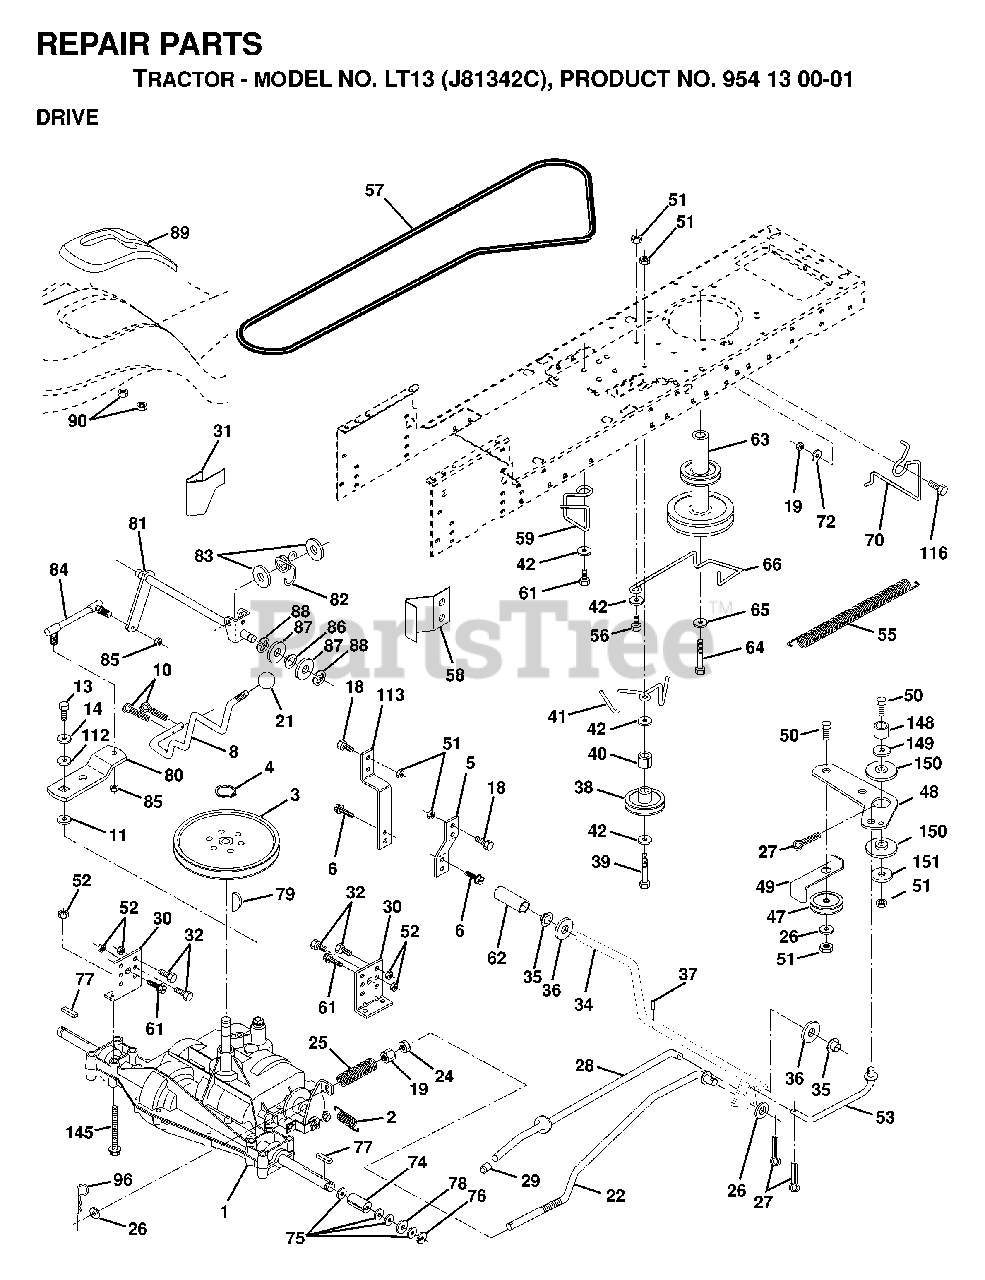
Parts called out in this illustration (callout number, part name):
2	SPRING,BRAKE RETURN
3	PULLEY TRANS
4	RETAINING RING LT
5	STRAP TORQUE
6	SCREW
8	ROD SHIFT FENDER
10	PIN COTTER
11	BLADE 42"
13	BOLT 1/4-28X3/4
14	LOCKWASHER
15	BOLT HEX 5/16-18 GR 5
19	NUT
21	KNOB.DELUXE.(PISTOL.GRIP).BLAC
22	ROD BRAKE
24	NUT
25	SPRING ROD LT
27	COTTER PIN
28	ROD BRAKE PARK LT
29	PLUNGER CAP
30	BRACKET TRANSAXLE
31	KEEPER BELT LH
32	BOLT
34	SHAFT, FOOT PEDAL
35	BEARING.NYLON
36	WASHER LT
37	DRIVE PIN
38	PULLEY.IDLER.FLAT
41	KEEPER, BELT IDLER
42	WASHER
47	IDLER PULLEY
48	BELLCRANK, CLUTCH
49	RETAIN BELT
50	BOLT
51	LOCKNUT
52	LOCKNUT
53	LINK, CLUTCH LT
55	SPRING, RETURN LT
59	KEEPER CENTER SPAN
61	SCREW
62	PEDAL COVER T
63	PULLEY ENGINE
64	BOLT
65	LOCKWASHER
66	KEEPER BELT ENGINE
70	KEEPER BELT ENG
74	SPACER AXLE
76	E-RING LT
77	SQUARE KEY
80	ARM SHIFT
82	SPRING,TORSION
83	WASHER
84	ROD,TIE
85	NUT LOCK CENTER 1/4 -28 FNTHD
88	KLIP RING
89	SHIFT CONSOLE
96	RETAINER M
112	WASHER LT
113	STRAP TORQUE LH LT
116	BOLT
148	GUIDE
149	SPACER RETAINER
150	BUSHING NYLON COLLERED
151	WASHER 12/32X2X10GA
